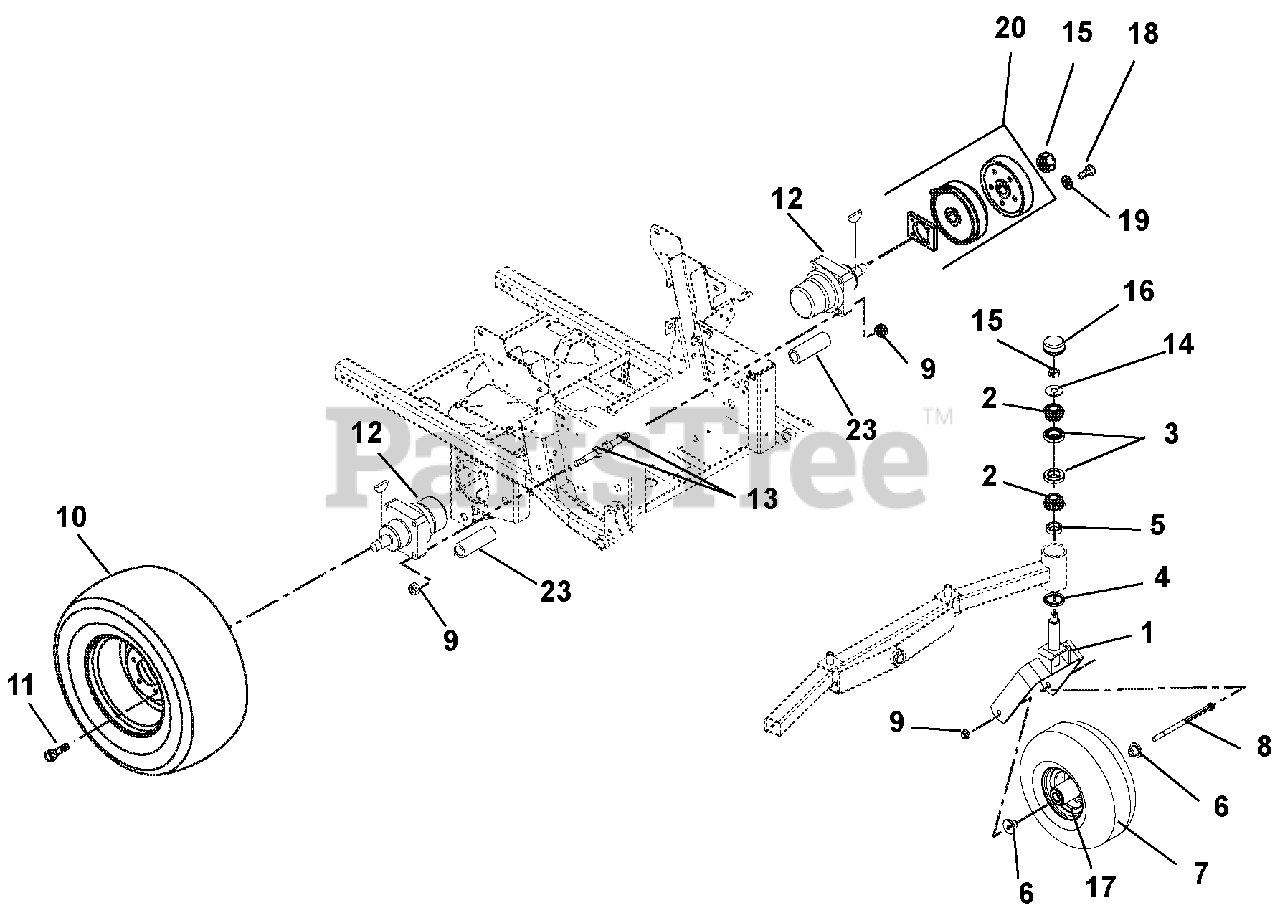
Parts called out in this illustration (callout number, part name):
1	Fork, Front
2	Bearing, Cone
3	Bearing, Cup 2.328 x .465
4	Bearing Seal 1.75 x 2.332 x .312
5	Spacer, 1.258ID x 1.750OD x .550
6	Spacer, Wheel
7	Wheel/Tire Assembly – 15 x 6-6, Smooth
7	Tire, 15 x 6-6, Smooth
8	Bolt, Hex .50-13 x 9.00 Grade 5
9	Nut, Locking Top Flange .50-13
10	Tire/Wheel Assembly, 24 x 11.50-12
10	Tire, 24 x 11.50-12
11	Bolt, Lug .50-20 x 1.38
12	Wheel Motor, Parker
13	Bolt, Wheel Motor .50-13 x 5.00
14	Washer, Flat Steel, .812 x 2.00 x .148
15	Nut, Locking Jam Patch 1.00-20
16	Cap, Dust
17	Bearing, 25mm I.D. x 52mm OD x 15mm
18	Bolt, Hex .31-18 x 1.50 Grade 8 EP30
19	Washer, Lock .31 x .078
20	Kit, Parking Brake Service
21	Key, Woodruff .31 x 1.00
22	Kit, Parker TF Motors Seal
23	Bushing, Sleeve .513 x .748 x 2.129
